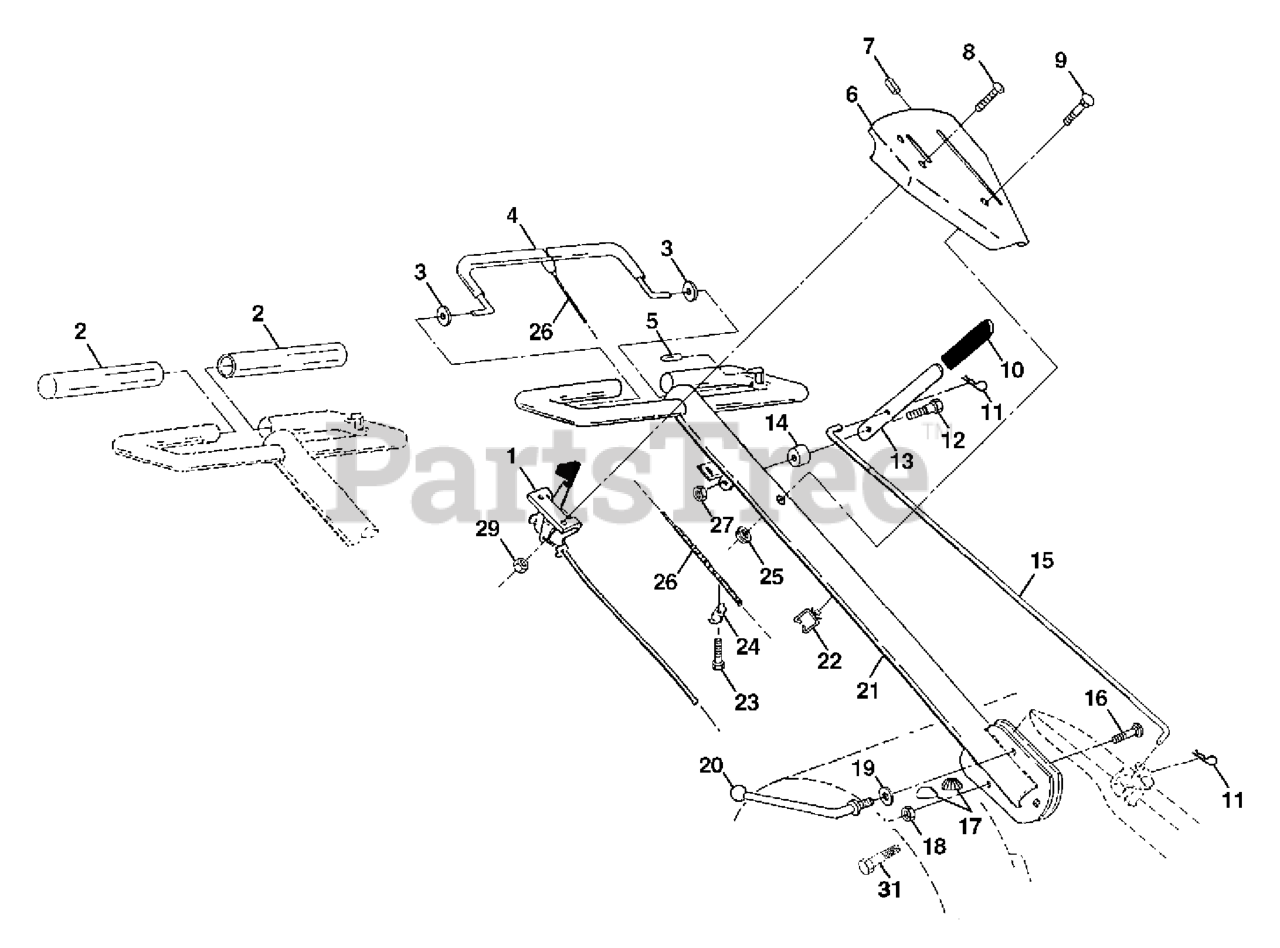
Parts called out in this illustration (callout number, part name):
1	THROTTLE.CONTROL.CRT.TILLER
2	GRIP.HANDLE.TILLER
3	GROMMET HANDLE
4	BAR ASSEMBLY, CONTROL
6	PANEL, CONTROL
7	BUSHING SPLIT
8	SCREW.PNHD.10-24
9	BOLT.5/16-18X2.5
10	GRIP, HANDLE
11	RETAINER M
12	SHOULDER BOLT ST
13	HANDLE, SHIFT
14	GROMMET.RUBBER.CRT.TILLER
15	ROD, SHIFT
16	BOLT D
17	LOCK.HANDLE.CRT
19	WASHER CRT
20	LEVER.LOCK.CRT
21	HANDLE
22	CLIP CABLE
23	TAPPING SCREW
24	CONDUIT.CLIP.PLATED
25	NUT.CENTERLOCK.5/16-
26	CABLE, CLUTCH
27	NUT T
29	NUT **
31	BOLT.PIVOT
